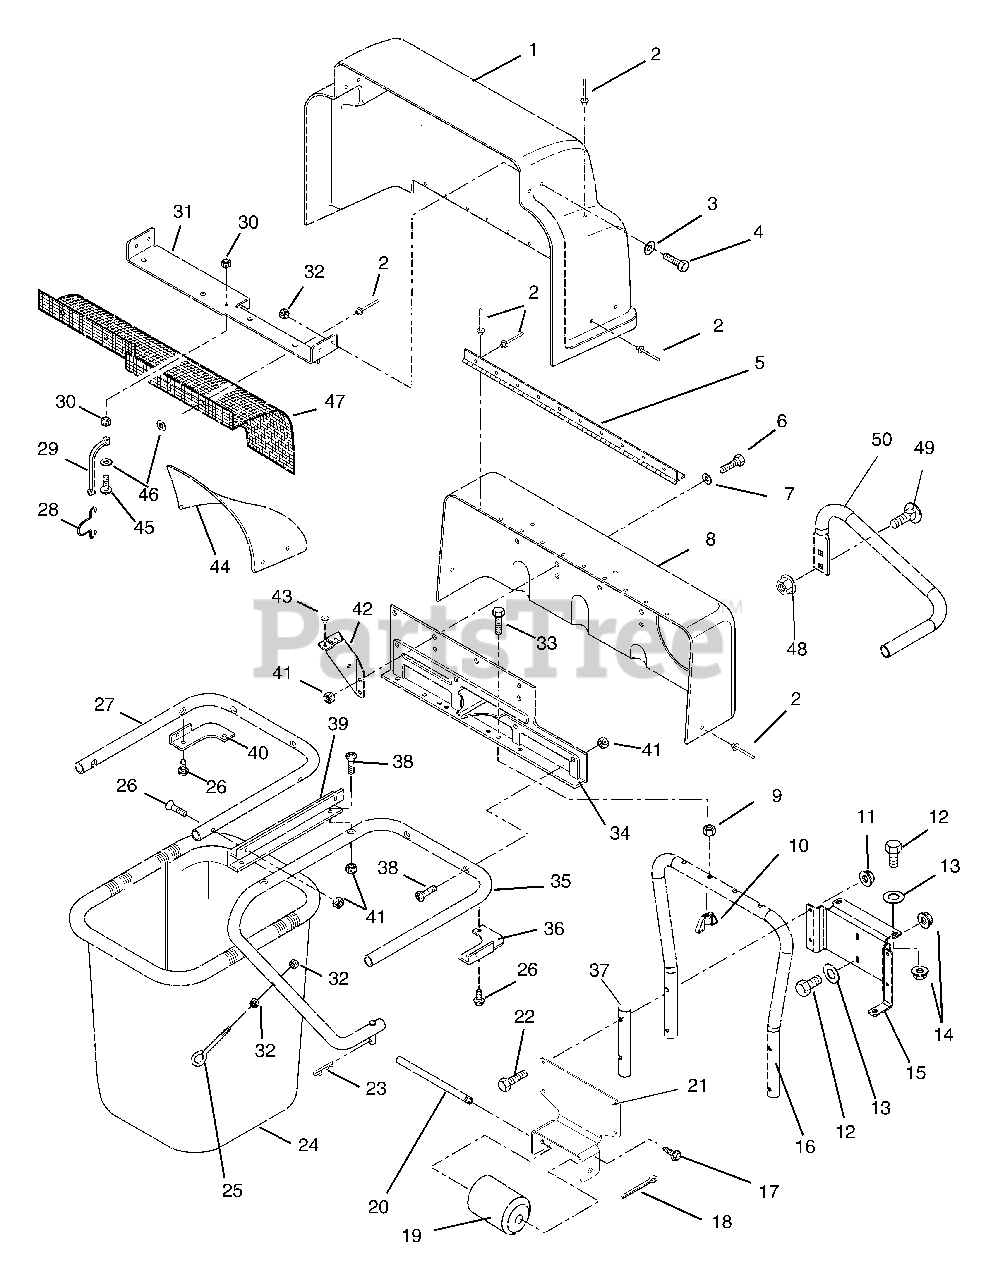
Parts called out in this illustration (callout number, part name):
1	Hinged Cover w/Decals
2	Rivet-Pop .187 x .402
3	Washer-Flat-Steel .281 x .62 x .065
4	Bolt-Hex .25-20 x .50 Grade 5
6	Bolt-Hex .31-18 x .75 Grade 2
7	Washer-Flat-Steel .328 x.875 x .062
8	Stationary Cover
9	Nut-Hex .31-18 Grade 2
10	Nut-Wing .312-18
11	Nut-Locking-Top-Flange .31-18
12	Bolt-Hex .38-16 x 1.00 Grade 5
13	Washer-Flat-Steel.38 x .875 x .083
14	Nut-Locking-Top-Flange.38-16
15	Bracket, Bagger Mount
17	Screw
18	Cotter Pin
20	Roll Pin
22	Bolt-Hex .31-18 x 1.50 Grade 5
23	Pin-Hair Internal .08 x .38 x 1.42
23	(Gravely Part Number)
24	Grass Bagger Basket
24	(Gravely Part Number)
26	Screw-Tapping .31-18 x .50
27	Center Tube
27	(Gravely Part Number)
28	(Gravely Part Number)
29	Battery Strap
29	(Gravely Part Number)
30	Nut-Locking Top 10-24
31	Cover Bracket
32	Nut-Locking-Center .250-20
33	Bolt-Hex .31-18 x 1.75 Full Thread
34	Mounting Bracket
35	Right Tube
36	Right Hand Corner Bracket
36	(Gravely Part Number)
37	Service Bar Brace (827016)
38	Screw-Machine .31-18 x 1.50
39	Tube Bracket
39	(Gravely Part Number)
40	Left Hand Corner Bracket
40	(Gravely Part Number)
41	Nut-Locking .312-18
42	(Gravely Part Number)
43	Rivet-Pop .187 x .527
43	(Gravely Part Number)
45	Screw-Machine 10-24 x .88
46	Washer-Flat-Steel .219 x.50 x .049
48	Nut-Flange, .375-16
49	Bolt-Round Head Square Neck .38-16 x .75 Grade 5
50	Support, 28-Inch Bagger Tube
